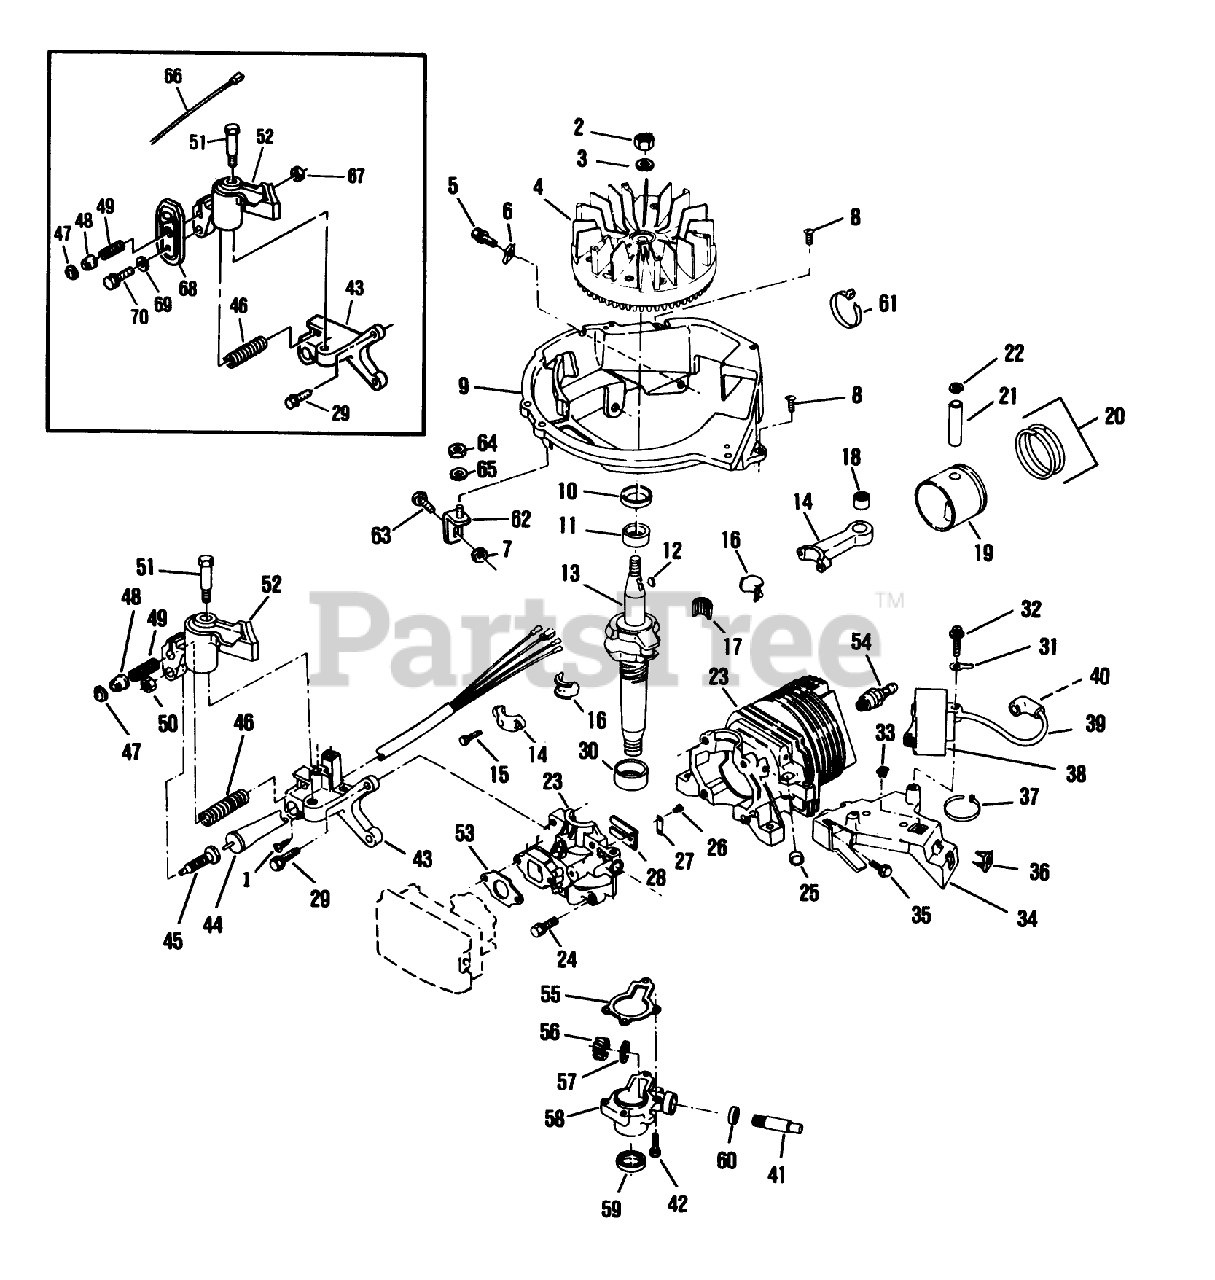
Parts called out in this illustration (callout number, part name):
1	SCREW F
2	NUT
4	FLYWHEEL ASSY F
5	SCREW-SEMS
7	NUT-LOCK F
8	SCREW F
9	BASE SHROUD F
11	BEARING V
12	KEY
15	SCREW-HSH
16	LINER ASM
18	BEARING AY F
22	RING-RETAINING
24	SCREW S
25	PLUG-CORE VF
27	PLATE-BACKUP, REED
30	BEARING S
31	TERMINAL S
33	NUT-CLIP
34	BRACKET S
36	NUT-CLIP
39	HT LEAD&COVER XEV
43	BRACKET-BRAKE F
45	PLUNGER S
46	SPRING-BRAKE
47	RETAINER S
48	ACTUATOR-LEVER, BRAKE
49	SPRING
53	GASKET CARB S
55	GASKET S
56	GEAR, DR SHAFT S
57	THRUST WASHER
59	SEAL-OIL
60	SEAL S
62	BRACE AY F
63	BOLT F
64	LOCKNUT E
65	WASHER S
66	WIRE LEAD AY F
67	NUT C/LOCK E
69	WASHER
